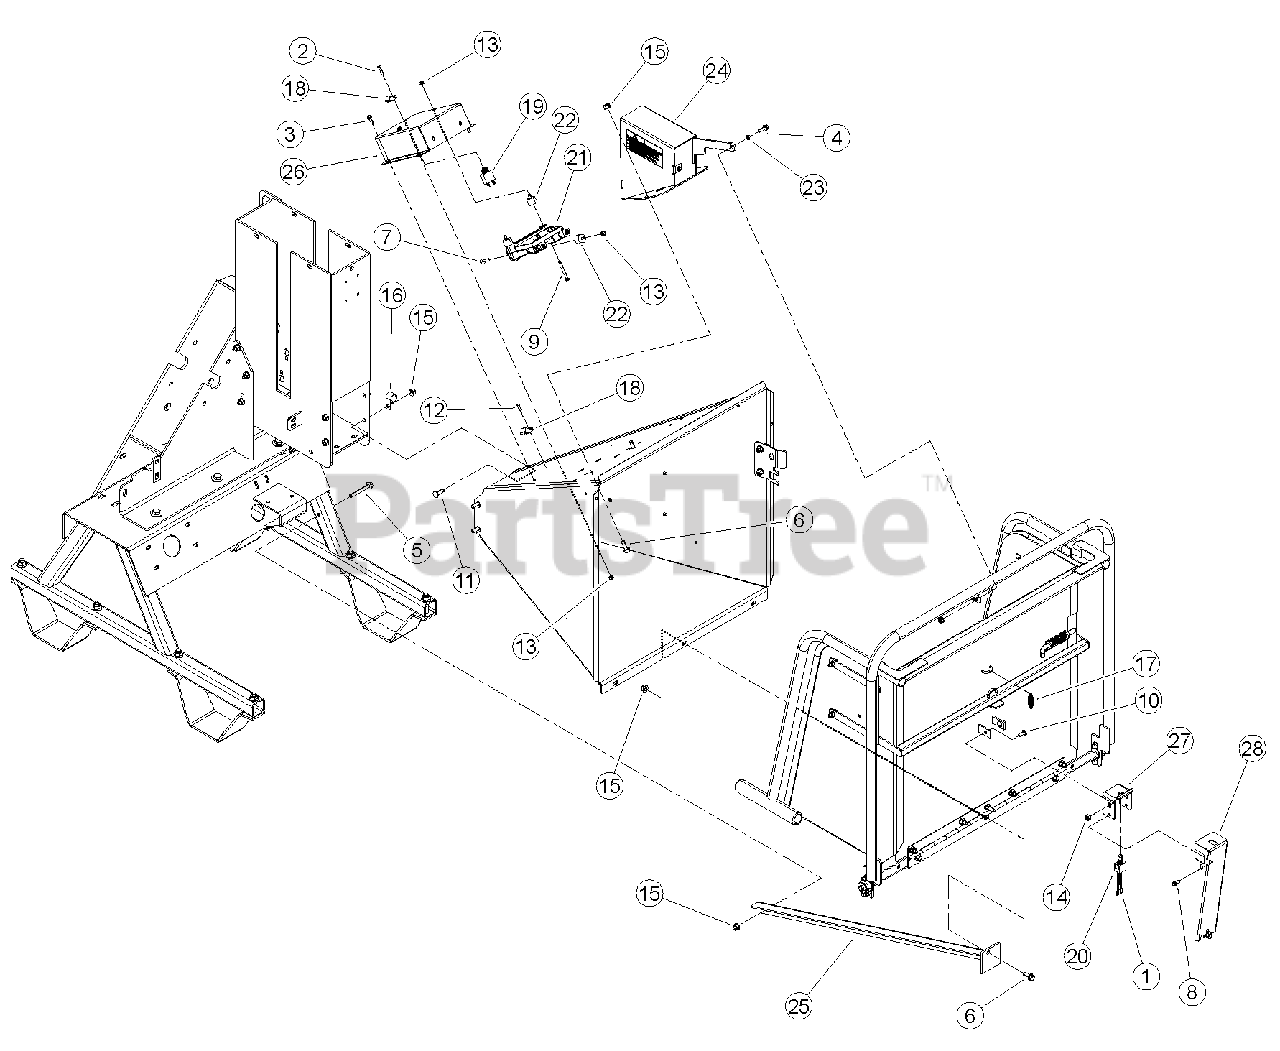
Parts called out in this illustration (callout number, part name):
1	CONNECTOR, 1/4 QD MALE
2	BOLT, 1/4 X 1 GR5 HEX HD ZP
3	BOLT, 1/4-20 X 3/4 HWH GR5 CZP
4	BOLT, 5/16 X 1 FLANGE NC
5	BOLT, 3/8 X 3 FLANGE NC
6	BOLT, 3/8 X 1 FLANGE NC
7	BOLT, 1/4 X 1-1/4 FLANGE NC
8	SCREW, 11/32 X 7/8 HWH AB THREAD ZP
9	BOLT, 1/4 X 2-1/4 G5 HCS ZP
10	BOLT, 5/16 X 7/8" GR5 NC ZP
11	BOLT, 3/8 X 1-1/4" GR5 NC ZP
12	RIVET, AL BLIND 1/4 X 3/4 DOME HEAD
13	NUT, 1/4-20 NYLOCK-FLANGE
14	NUT, 5/16-18 NYLOCK-FLANGE
15	NUT, 3/8-16 NYLOCK FLANGE
16	CLAMP, 1" COATED METAL
17	SPRING, 1/2 X 2.00 LG ZP
18	CLAMP, CABLE MOUNT
19	CIRCUIT BREAKER, 10 AMP RESETTABLE
20	SWITCH, MOMENTARY IP67 NORMALLY ON (FOR SERVICE ORDER KIT 77536-00, CONTROL SWITCHES)
21	CONTROLLER, PLUS 1 CHIPPER
22	BUMPER, 1" OD W/ 1/4" STUD
23	SPACER, IDLER PIVOT
24	ASSEMBLY, SWITCH BOX
25	WELDMENT, CHUTE SUPPORT
26	ENCLOSURE, PLUS 1 MOUNT
27	BRACKET, SWITCH (FOR SERVICE ORDER KIT 77536-00, CONTROL SWITCHES)
28	SHIELD, SAFETYBAR SWITCH
